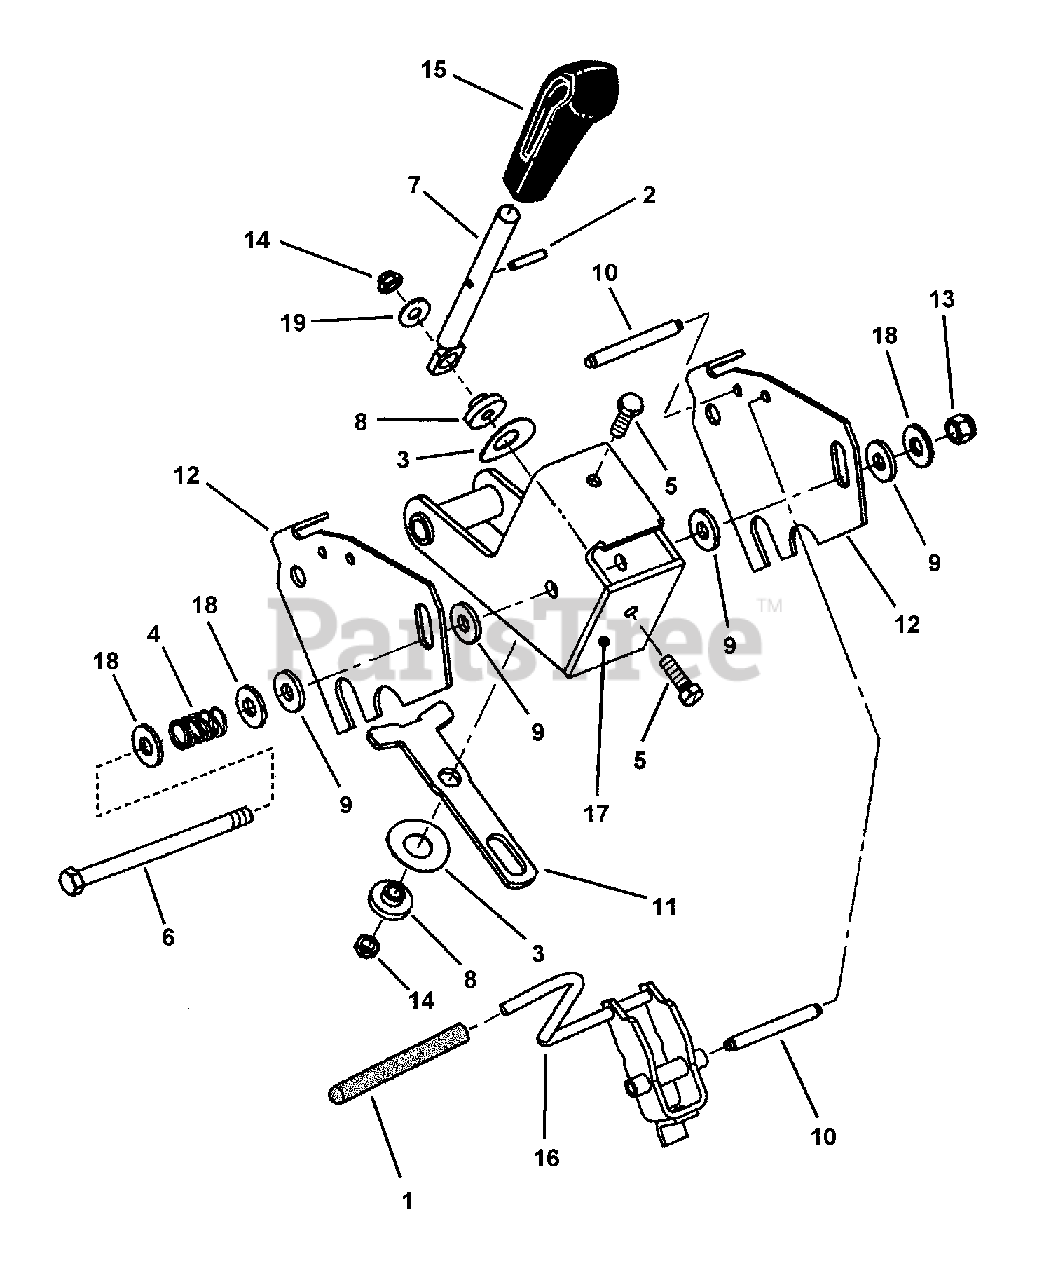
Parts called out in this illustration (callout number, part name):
1	GRIP, Vinyl
2	PIN, 3/16 x 1" Roll
3	WASHER, 5/8" I.D., 1-1/4" O.D. Belleville
4	SPRING, Compression
5	BOLT, 5/16-18 X 1 GD5 YZ
6	BOLT, 3/8-16 X 5" GD5 YZ
7	LEVER
8	BUSHING
9	WASHER, Slipper
10	PIN, Shoulder
11	CAM, Track
12	PLATE, Speed, Accutrack
13	NUT, 3/8-16 HEX NYLON LOCK
14	NUT, 5/16-18 Hex Top Lock, GR B
15	HANDLE, Shift Lever
16	WELDMENT, Neutral Latch
17	TRACK, Welded
18	WASHER, 3/8" USS
19	WASHER, .33 x .88 x .09 Flat
